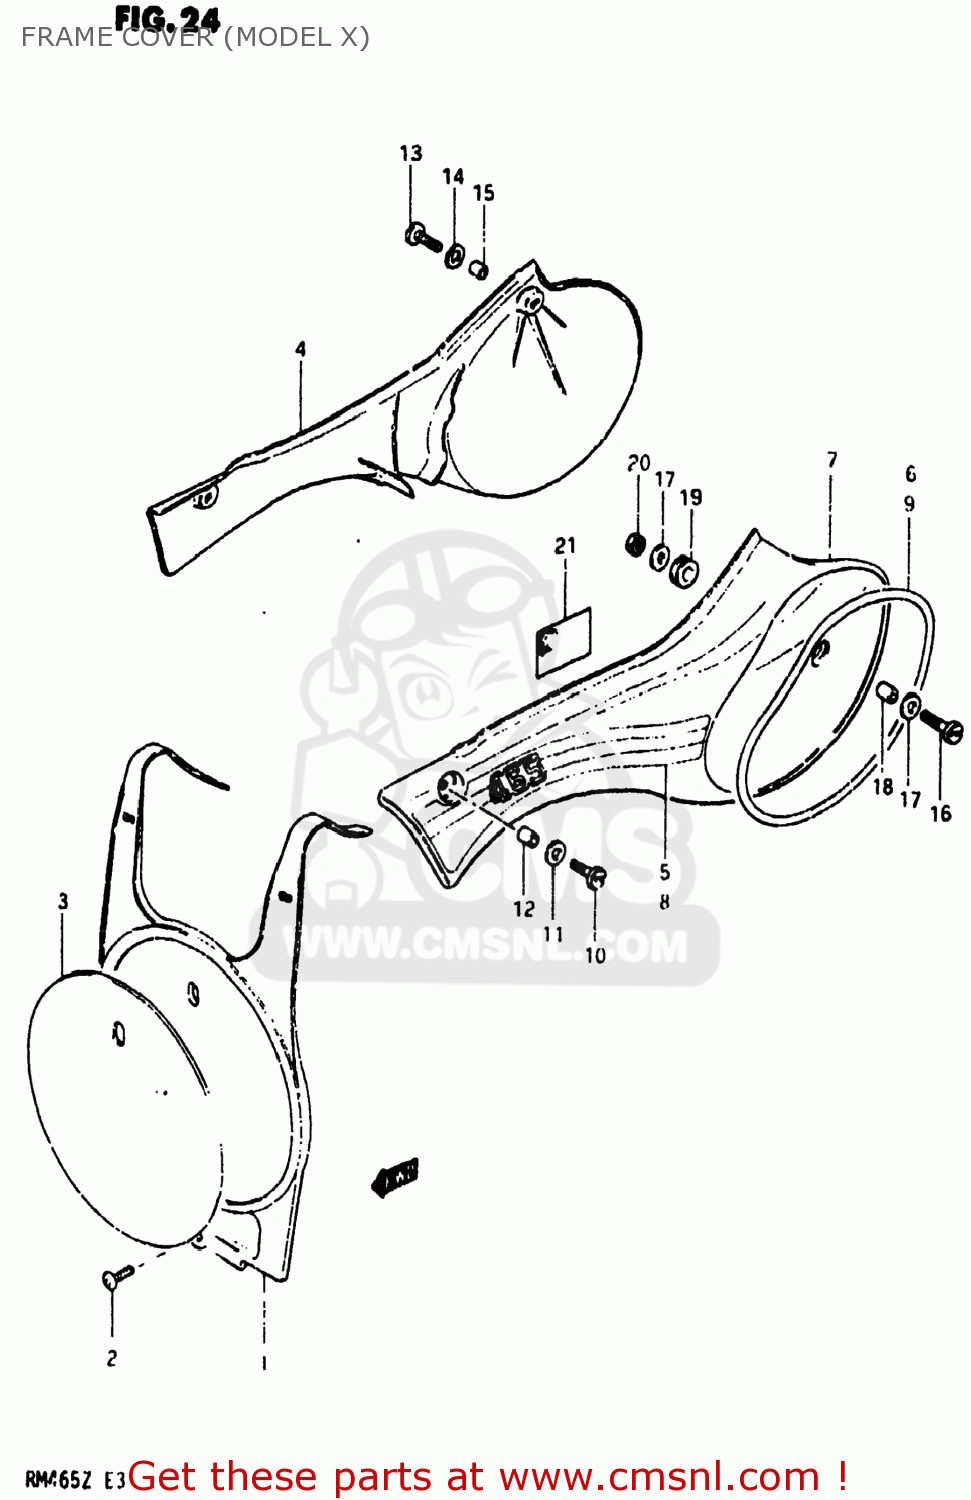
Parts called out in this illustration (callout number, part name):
1	PLATE,NUMBER,FRONT
2	(5X20) CROSS SCREW
3	EMBLEM,FRONT NUMBER PLATE
4	COVER,FRAME,RIGHT
5	TAPE,FRAME COVER
6	TAPE,FRAME COVER
7	COVER,FRAME,LEFT
8	TAPE,FRAME COVER
9	TAPE,FRAME COVER
10	SCREW(6X25)
11	WASHER FRAME COVER
12	SPACER,FRAME COVER,FRONT
13	SCREW
14	WASHER FRAME COVER
15	SPACER FRAME COV RR
16	SCREW(6X25)
17	WASHER FRAME COVER
18	SPACER,FRAME COVER,FRONT
19	CUSHION
20	NUT 6MM
21	HEAT SHIELD,FRAME COVER
